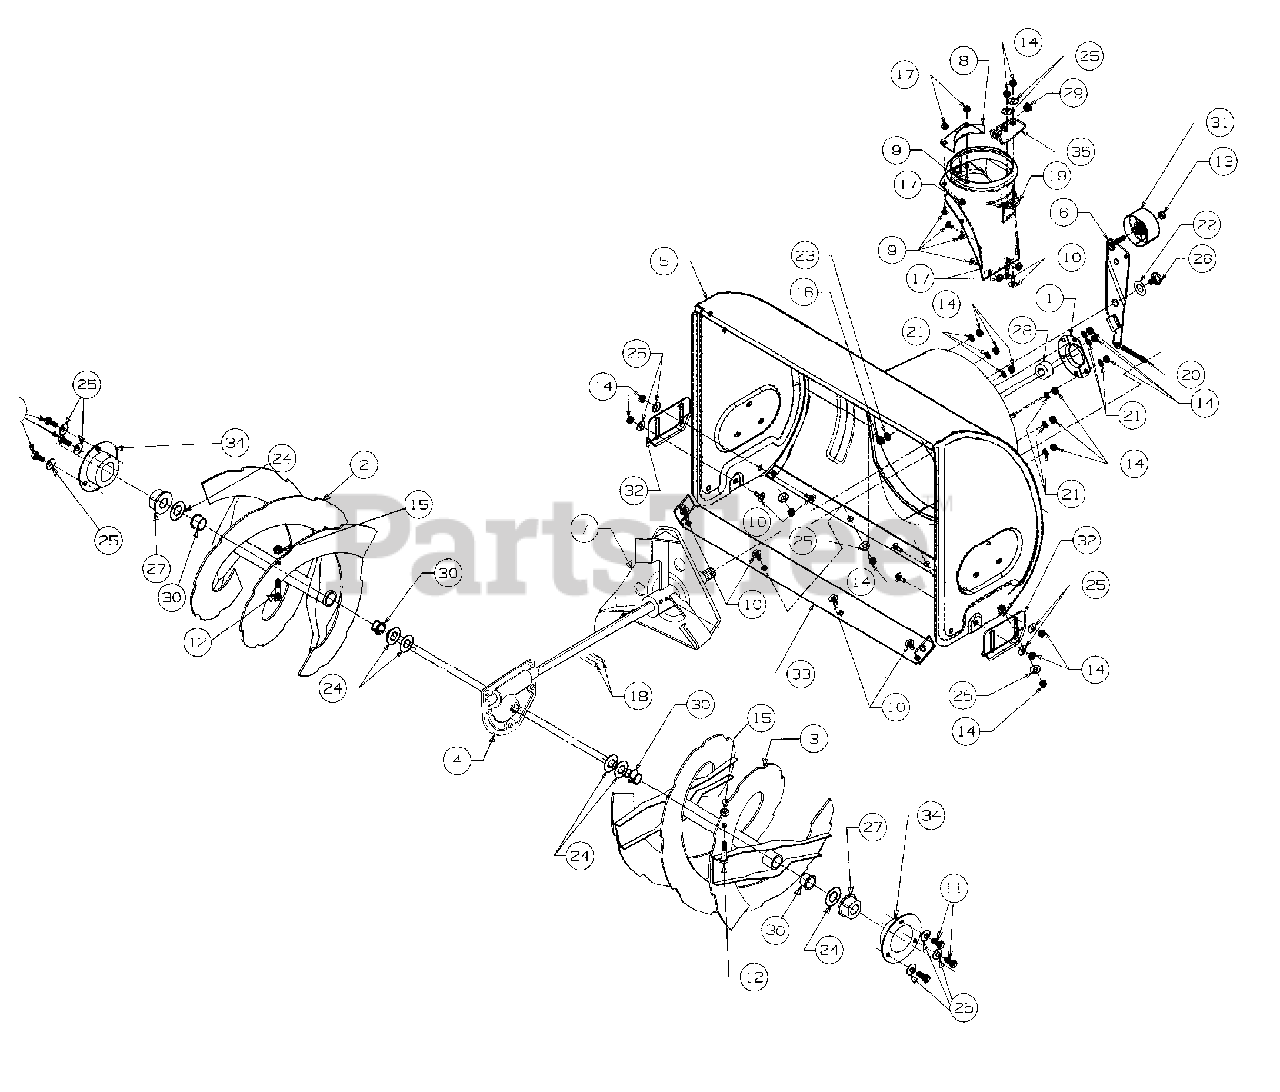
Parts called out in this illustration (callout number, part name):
1	Housing-Bearing
9	Screw - Carriage
10	Screw - Carriage
11	Screw - Hex
12	Shear Bolt
13	Nut - Hex Lock
14	Nut - Hex
15	Nut - Hex
16	Nut - Hex
17	Nut - Hex Lock
18	Pin - Spring
19	Adapter - Chute
20	Spring
21	Washer - Lock
22	Washer - Flat
23	Washer - Lock
24	Washer - Flat
25	Washer - Bell
26	Screw - Shoulder
27	Bearing - Flange
28	Bearing - Ball
29	Bushing - Plastic
30	Bushing - Flange
31	Idler - Flat
